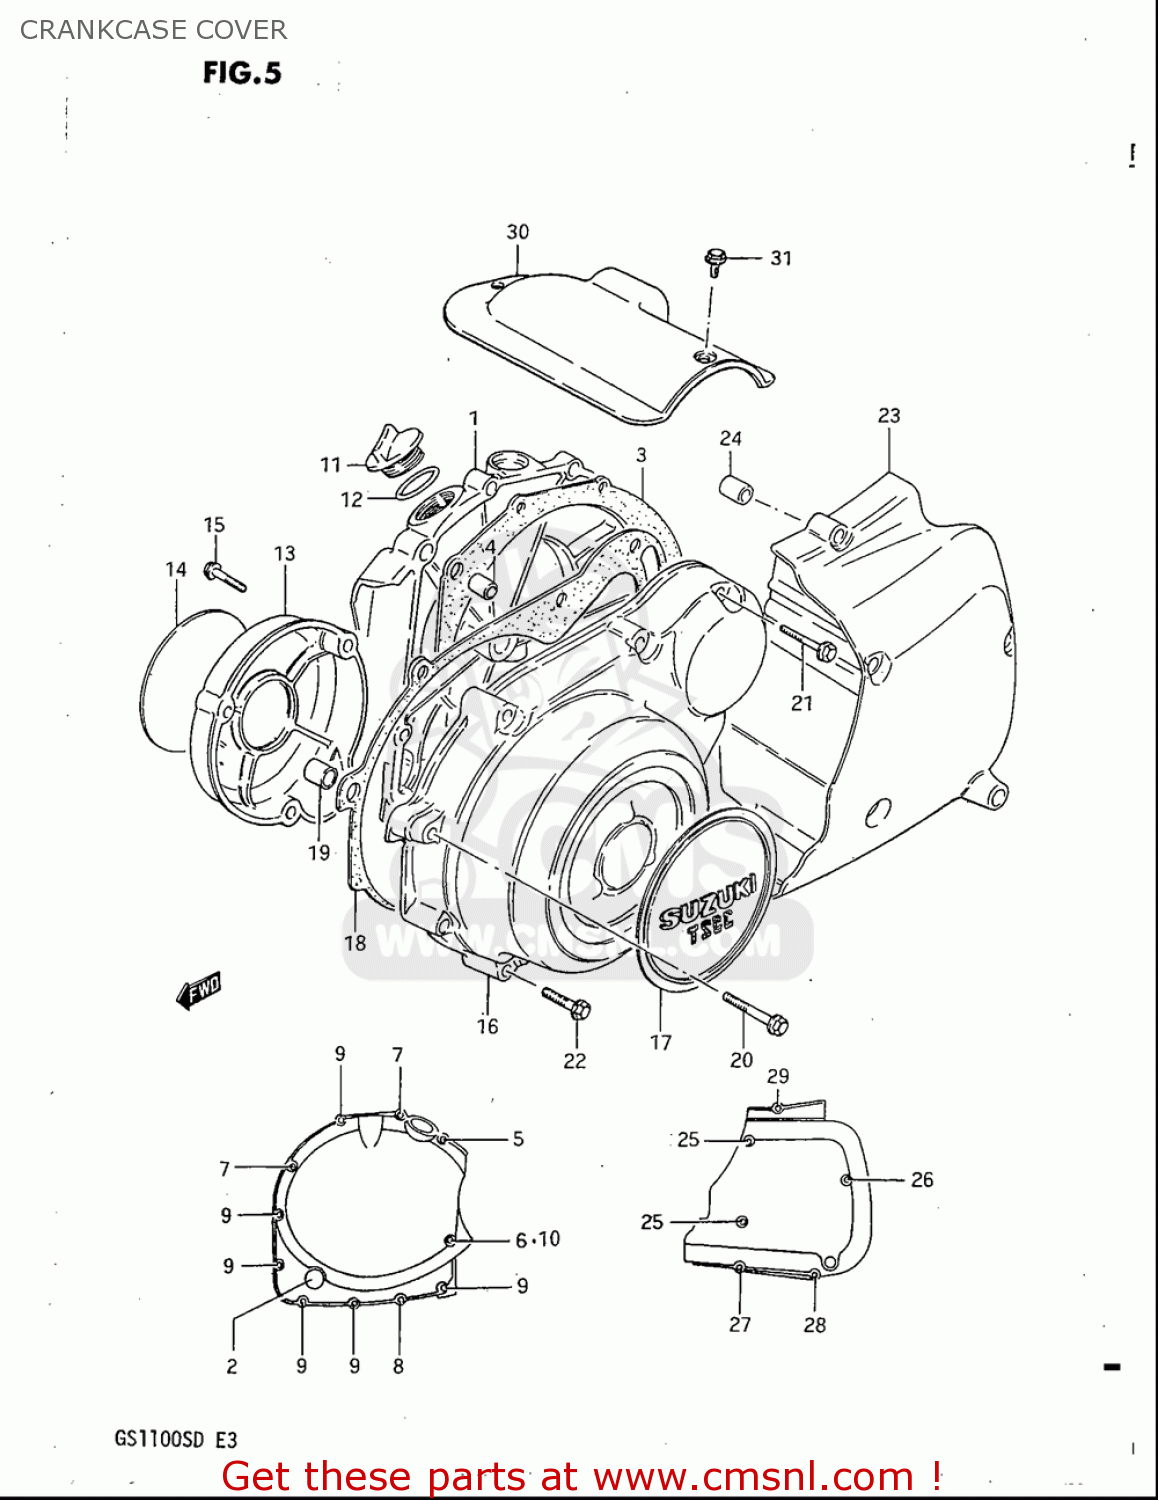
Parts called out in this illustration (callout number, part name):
1	COVER,CLUTCH
2	LENS,OIL LEVEL CHECK
3	GASKET,CLUTCH COVER (NAS)
4	PIN
5	BOLT
6	BOLT
7	BOLT
9	SCREW
10	GASKET(5.8X13X1.2) (NAS)
11	PLUG SET
12	O RING(D:2.2,ID:32)
13	COVER,CONTACT BREAKER
14	EMBLEM
15	BOLT
16	COVER,MAGNETO
17	EMBLEM,MAGNETO COVER
18	GASKET,MAGNETO COVER (NAS)
19	PIN
20	BOLT
21	BOLT
22	BOLT
23	COVER,ENGINE SPROCKET
24	PIN
25	BOLT
26	BOLT, CRANKCASE (6X85)
27	BOLT
28	BOLT
29	BOLT
30	COVER,STARTER MOTOR
31	BOLT
